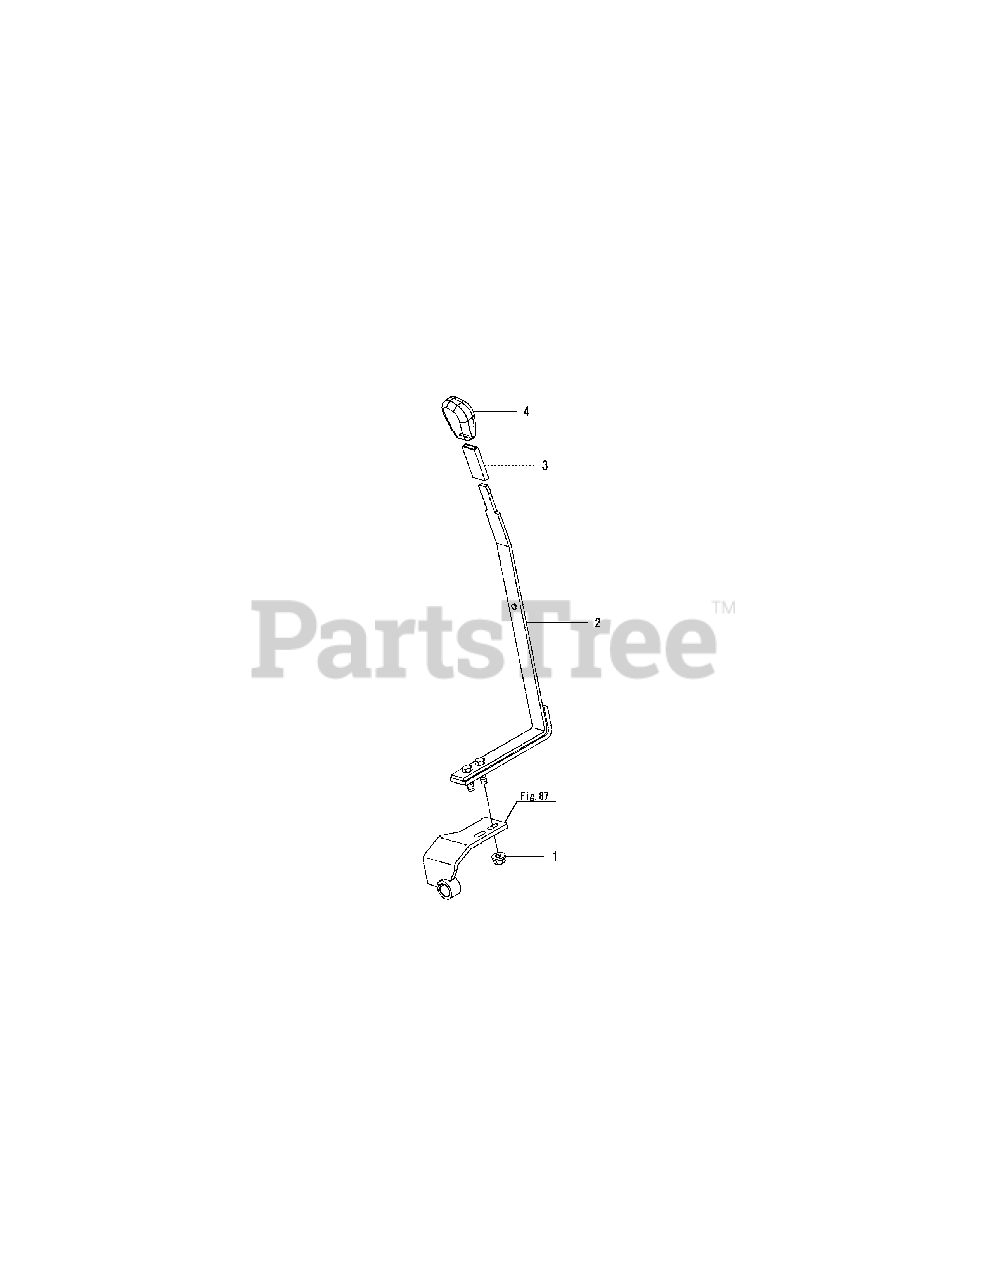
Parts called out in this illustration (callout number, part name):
1	NUT W/WASHER 8
2	LEVER ASSY, LIFT
3	PIPE, PROTECTOR
